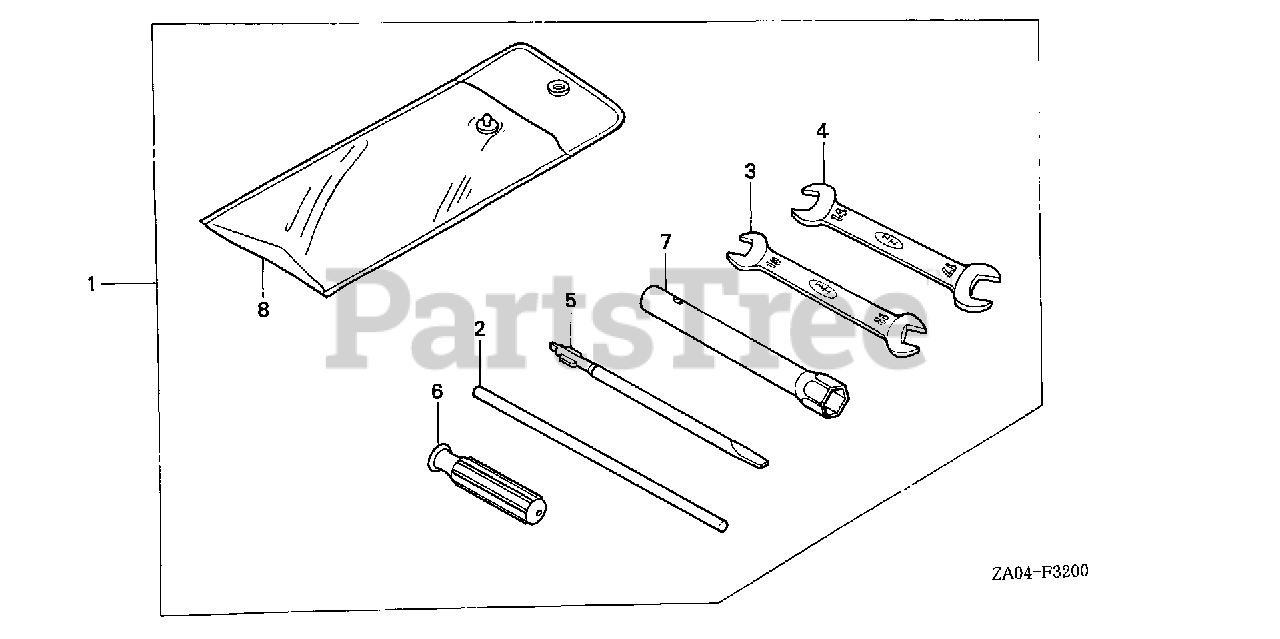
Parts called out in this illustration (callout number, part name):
1	TOOL KIT (NOT AVAILABLE)
2	BAR, PLUG WRENCH
3	SPANNER (10X12)
4	SPANNER (14X17)
5	DRIVER 3, MINUS SCREW (NO.2)
6	GRIP, SCREW DRIVER
7	WRENCH, BOX (P21)
8	BAG, TOOL (160MM)
